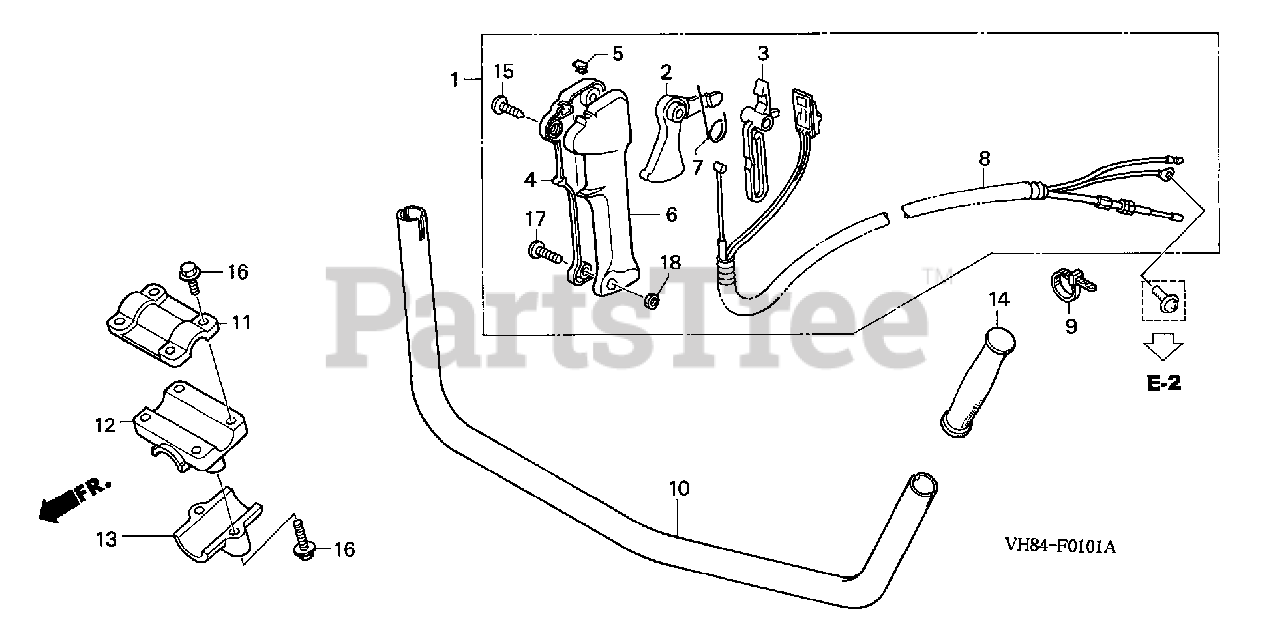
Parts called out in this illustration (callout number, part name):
1	LEVER ASSY., THROTTLE (U)(LEVER=YELLOW)
2	LEVER, THROTTLE (YELLOW)
3	LEVER, THROTTLE LOCK (YELLOW)
4	GRIP, R. THROTTLE LEVER
5	CAP, THROTTLE LEVER
6	GRIP, L. THROTTLE LEVER
7	SPRING, THROTTLE LEVER
8	WIRE HARNESS ASSY.
9	TIE, CABLE (157.5MM)
10	PIPE, HANDLE
11	HOLDER A, HANDLE
12	HOLDER B, HANDLE
13	HOLDER C, HANDLE
14	GRIP, HANDLE
15	SCREW, TAPPING (4X20)
16	BOLT-WASHER (5X28)
17	SCREW, PAN (5X30)
18	NUT, HEX. (5MM)
